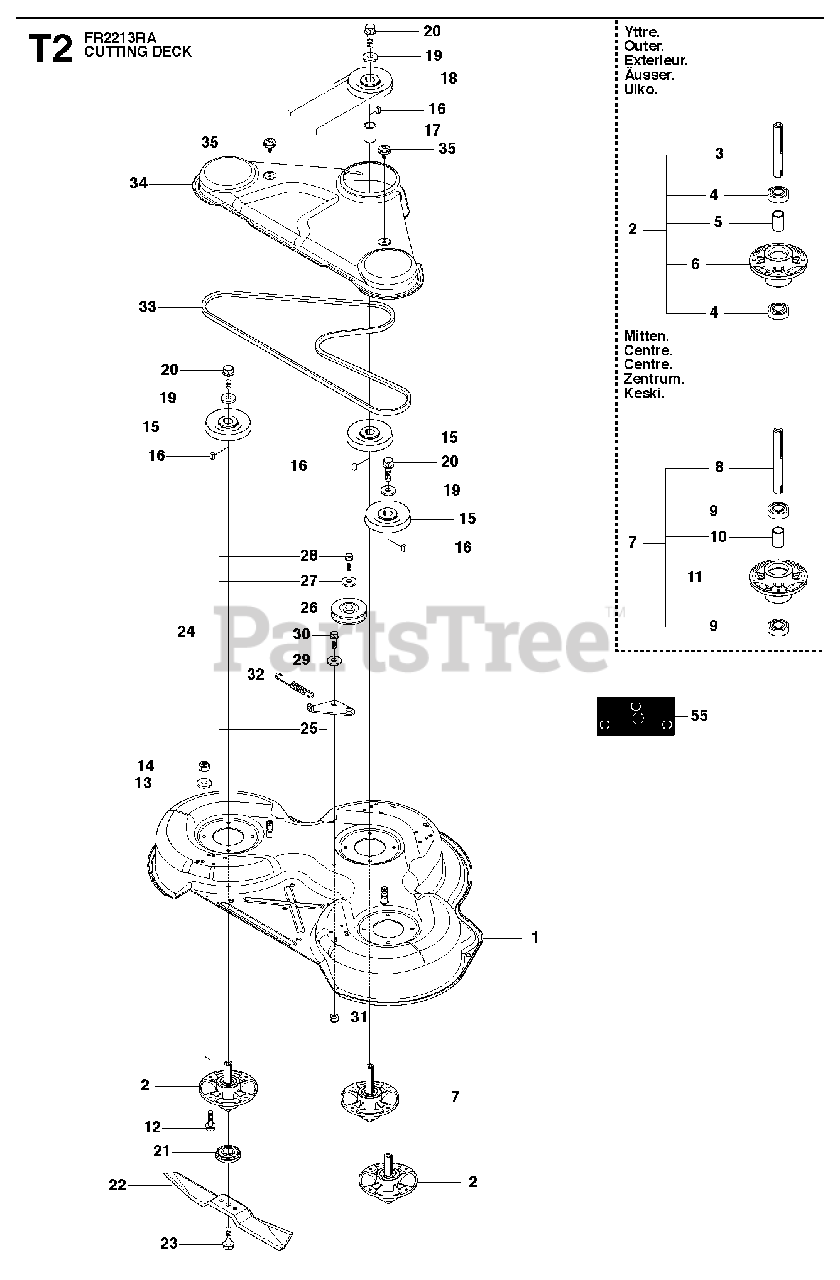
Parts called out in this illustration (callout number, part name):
2	RP SPINDLE ASSY
3	SHAFT
4	BEARING
5	SPACER
6	BEARING HOUSING
9	BEARING
10	SPACER
11	BEARING HOUSING
13	WASHER BRB 8.4X17
14	LOCKNUT M8
25	BRACKET
26	PULLEY
27	SPACER
28	BOLT
29	WASHER
31	LOCKNUT M8
